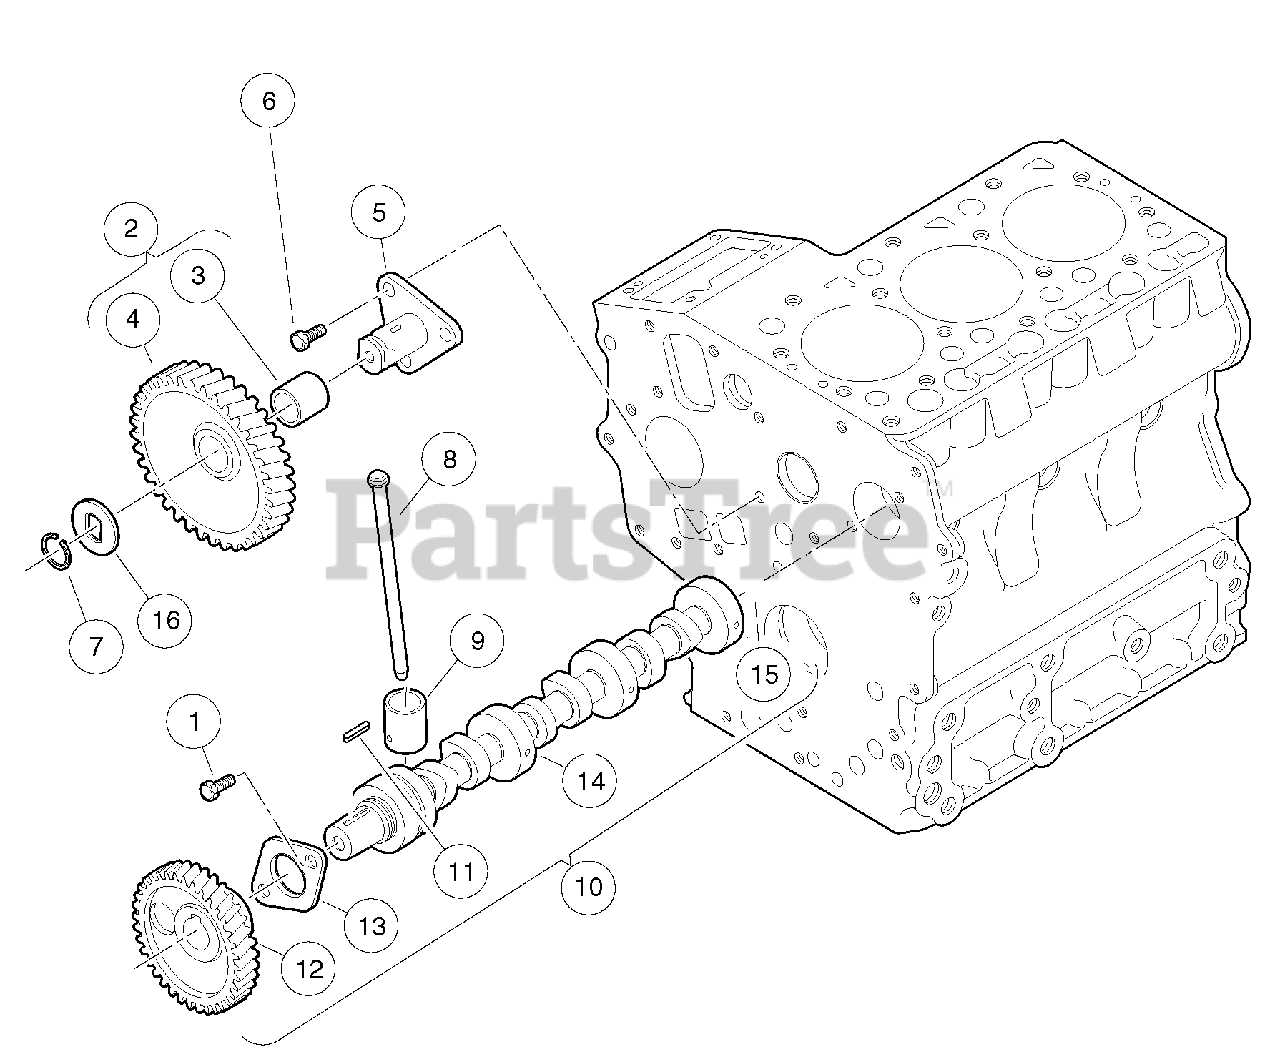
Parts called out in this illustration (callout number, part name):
1	Bolt, D722, Cam End
2	Gear, Idle
3	Bushing, D722 Idle Gear
4	Gear, Idle
5	Shaft, Idle Gear
6	Bolt, M6 X 1 X 14
7	Ring, Snap
10	Assy Camshaft, Long
11	Key, Feather, Long Camshaft
13	Stopper, Camshaft
14	Camshaft
15	Ball, Check
16	Collar, Idle Gear
